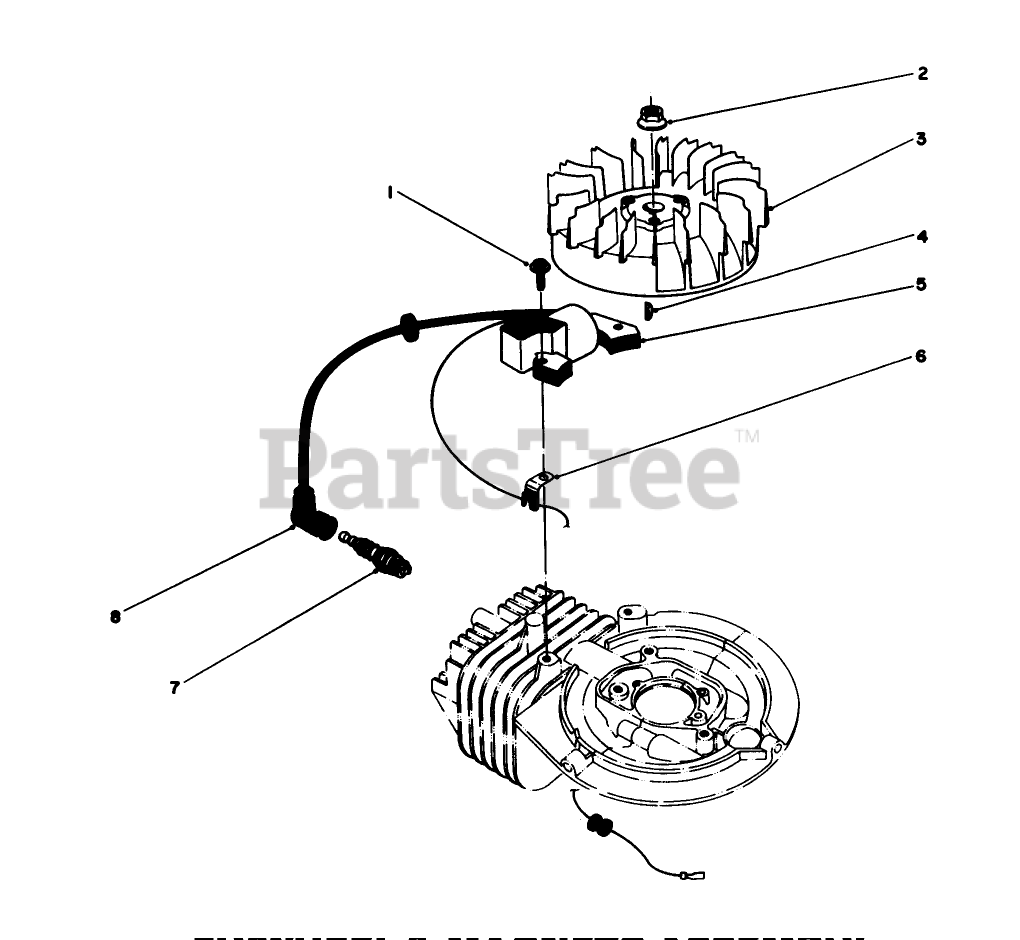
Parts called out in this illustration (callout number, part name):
3	FLYWHEEL
5	COIL-MAGNETO
6	CLAMP
8	CAP-SPARKPLUG
